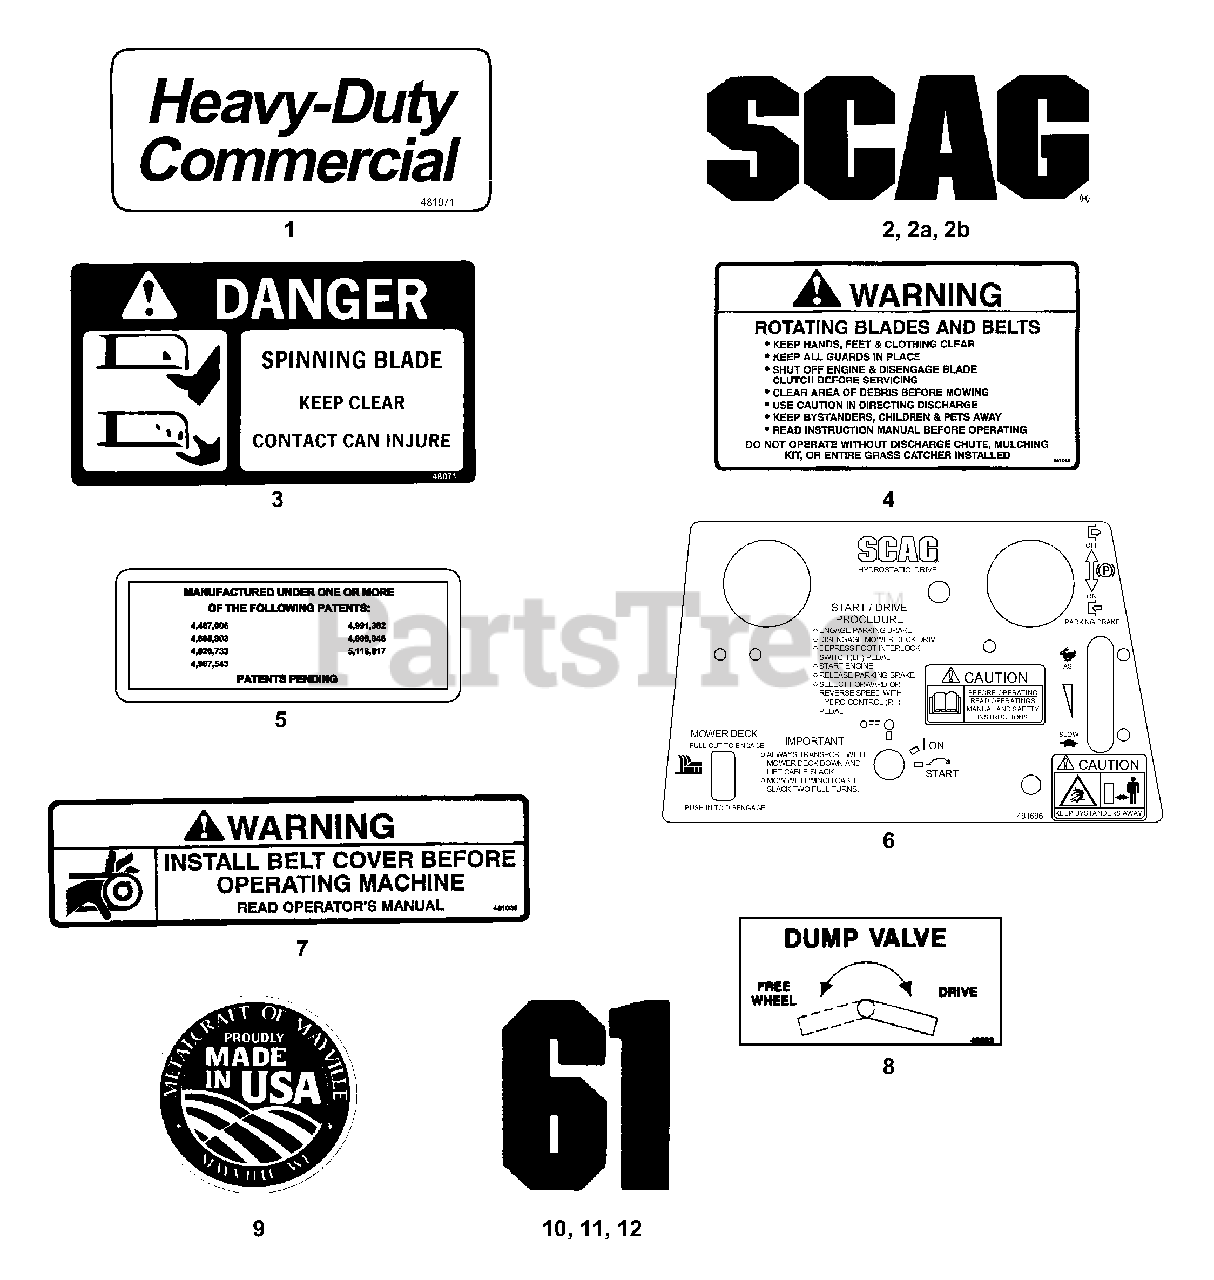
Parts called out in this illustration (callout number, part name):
1	Decal, Heavy Duty Commercial
2	Decal, Scag Logo (Cutter Deck)
2A	Decal, Scag Logo (Battery Box Front)
2B	Decal, Scag Logo Seatback
3	Decal, Danger-Spinning Blades
4	Decal, Warning-Rotating Blades
5	Decal, Patent
6	Decal, Instrument Panel
7	Decal, Warning-Belt Cover
8	Decal, Dump Valve
9	Decal, Metalcraft-Made In USA
10	Decal, 52
11	Decal, 61
12	Decal, 72
